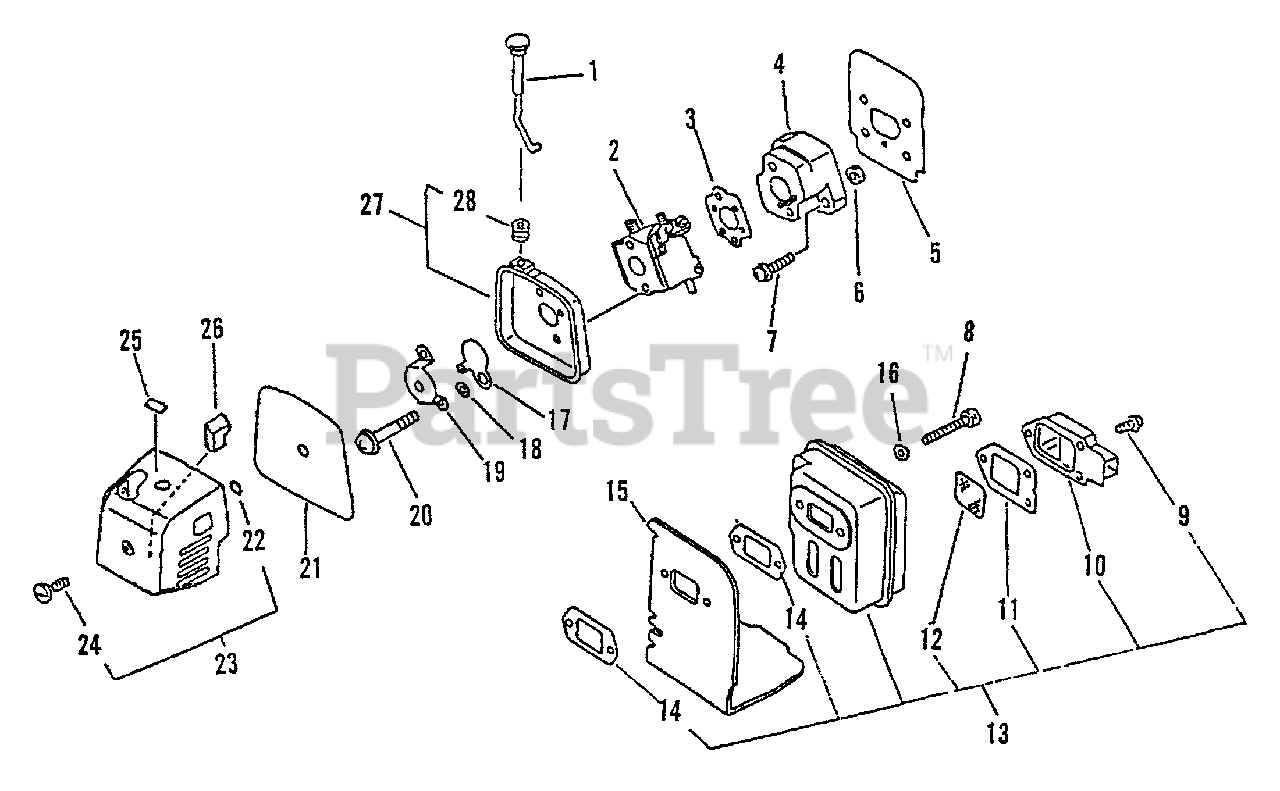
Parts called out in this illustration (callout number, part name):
1	ROD, CHOKE
2	CARBURETOR - C1U-K23
3	GASKET, INTAKE
4	INSULATOR, INTAKE
5	HEAT SHIELD, INTAKE
6	NUT M5
7	SCREW 5×20
8	BOLT 5×55
9	SCREW 4×10
10	GUIDE, EXHAUST - INNER
11	GASKET, EXHAUST
12	SCREEN, SPARK ARRESTER
13	MUFFLER ASSY
14	GASKET, EXHAUST
15	COVER, EXHAUST
16	WASHER, FLAT 5.5×10×0.8
17	SHUTTER, CHOKE
18	WASHER 5.2×8×0.8T
19	CASE, AIR FILTER
20	SCREW - 5×55
21	FILTER, AIR
23	AIR FILTER COVER ASSY
25	LABEL, CHOKE
27	GROMMET, CHOKE
28	CASE, AIR FILTER
